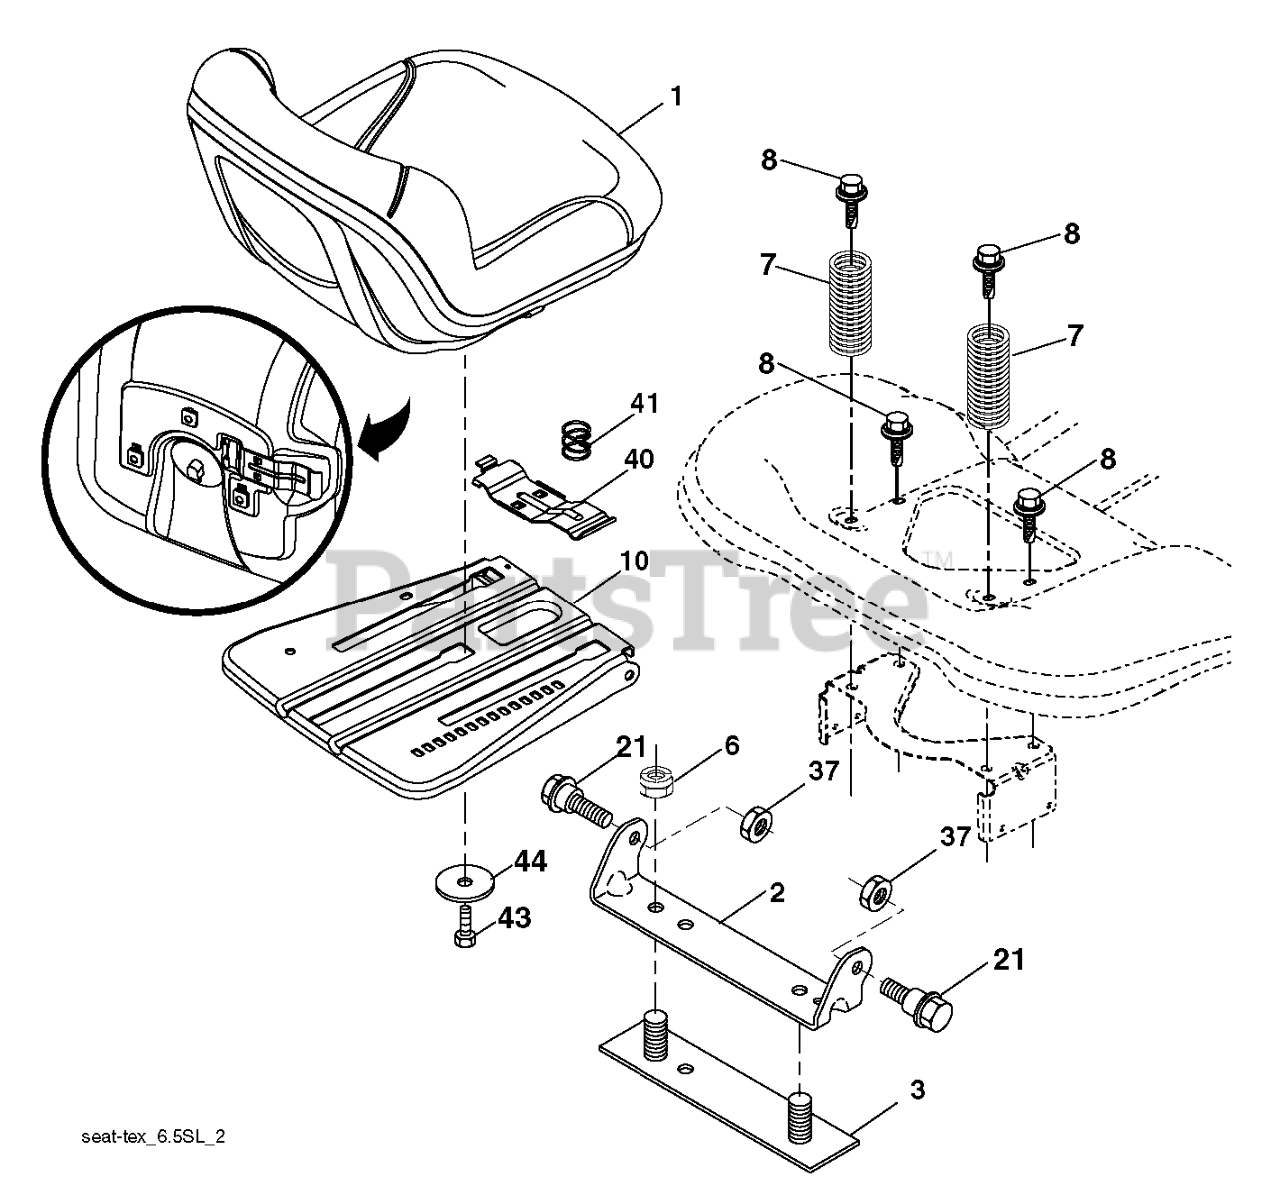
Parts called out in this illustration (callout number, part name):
1	RP SEAT, TH150, GREY, MILSCO
2	BRKT.PIVOT.FENDER
3	STRAP
6	NUT
7	SPRING COMPRESSION
8	BOLT.5/16-18UNCX3/4 W/SEMS.BLK
10	PAN.ASM.SEAT.3PT
21	BOLT.SHOULDER.5/16-18
37	NUT.71038.31-18.HEX.NYLOCK
40	HANDLE.SLIDE.SEAT.TEX.BLACK
41	SPRING.LATCH.SEAT.TEX
44	WASHER 13/32 X 2-3/8 X 12GA
